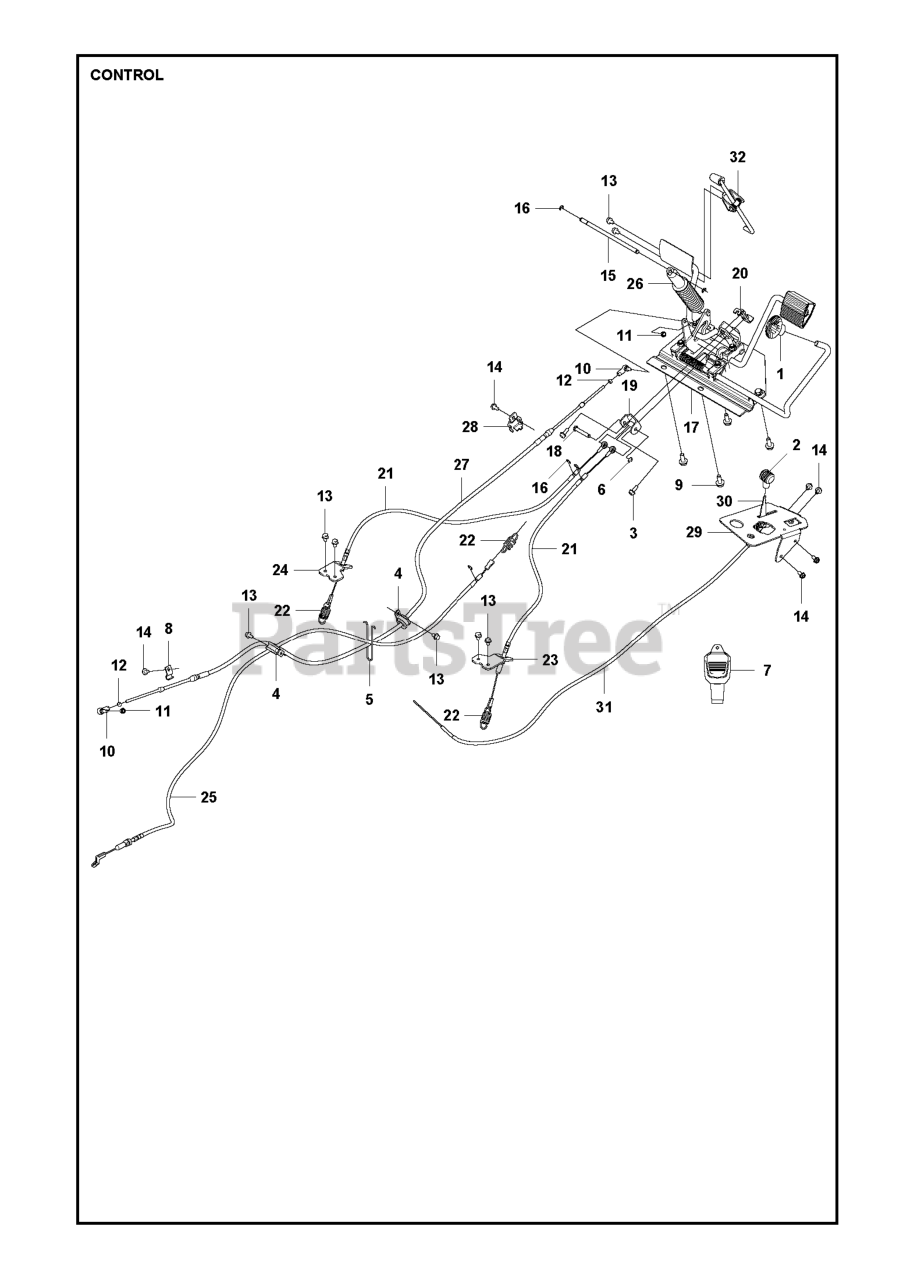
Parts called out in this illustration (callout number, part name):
1	KNOB, THREADED
3	SCREW
4	HOSE CLAMP
10	CONNECTOR, BALL JOINT
11	LOCKNUT M6
14	SCREW EHHFM
26	SHOCK ABSORBER
30	THROTTLE CONTROL ASSY SINGLE
32	BRAKE LEVER ASSY
